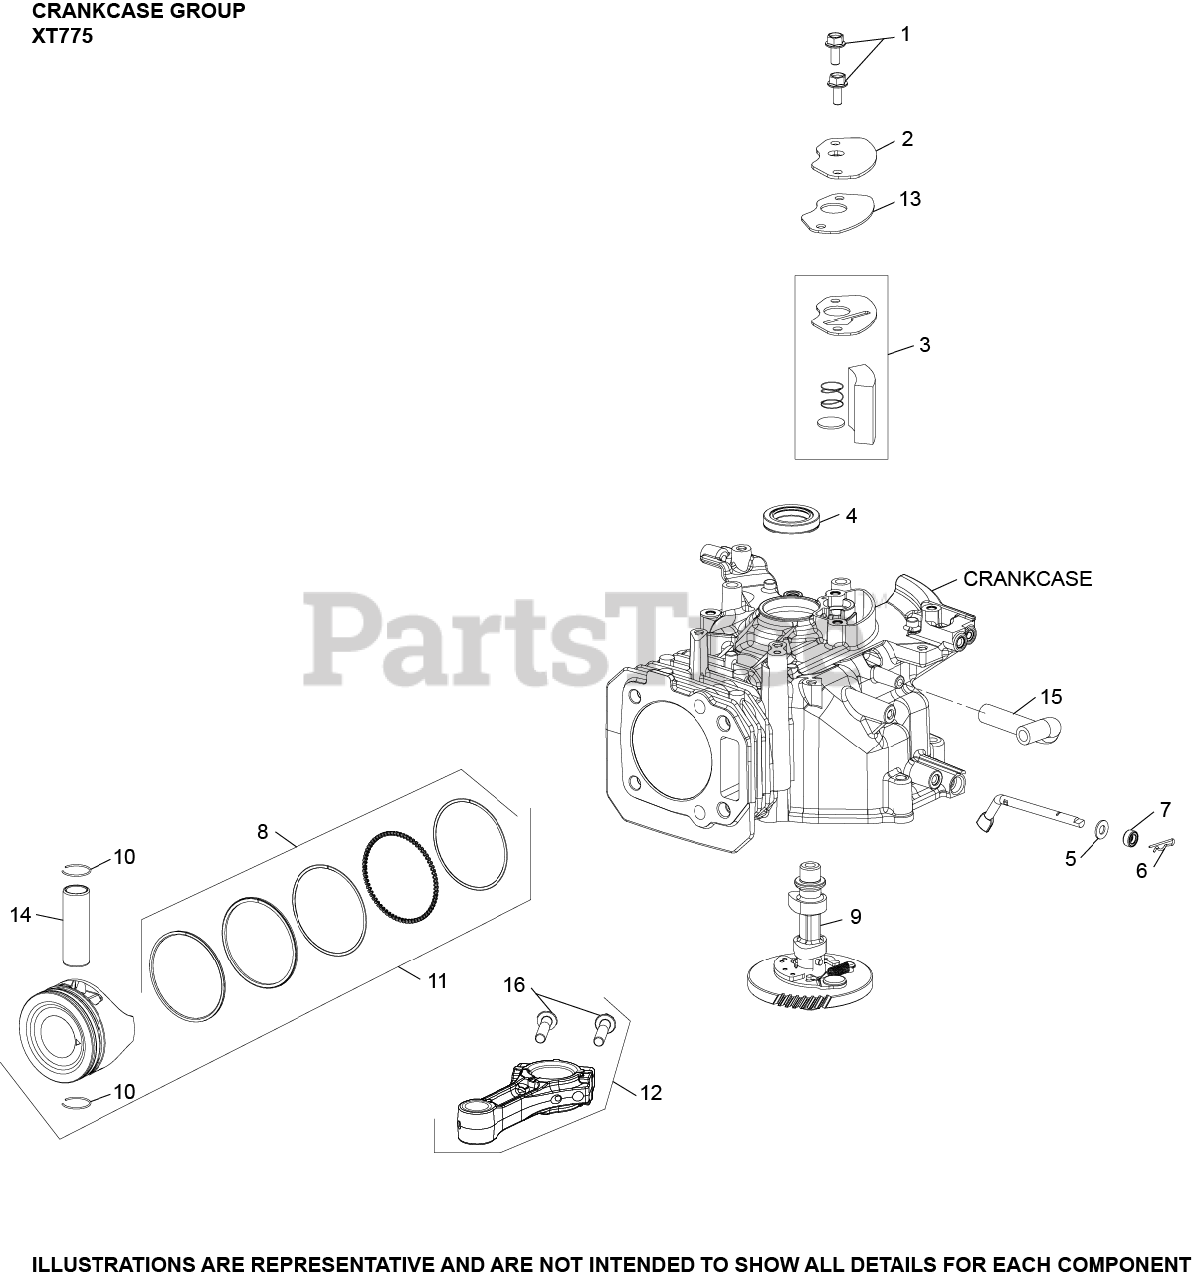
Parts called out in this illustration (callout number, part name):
1	SCREW, HEX FLANGE (M6) (CKY)
2	COVER, BREATHER
3	KIT, BREATHER FILTER
4	SEAL, CCASE/FLYWHEEL
5	WASHER, FLAT (DIA 13mm O.D.)
6	CLIP, GOVERNOR SHAFT
7	SEAL, OIL
9	CAMSHAFT ASSEMBLY
10	RETAINER, PISTON PIN
11	KIT, PISTON
12	CONNECTING ROD
13	GASKET, BREATHER COVER
14	PIN, PISTON
15	HOSE, BREATHER
16	SCREW, HEX FLANGE (M7) (CKY)
